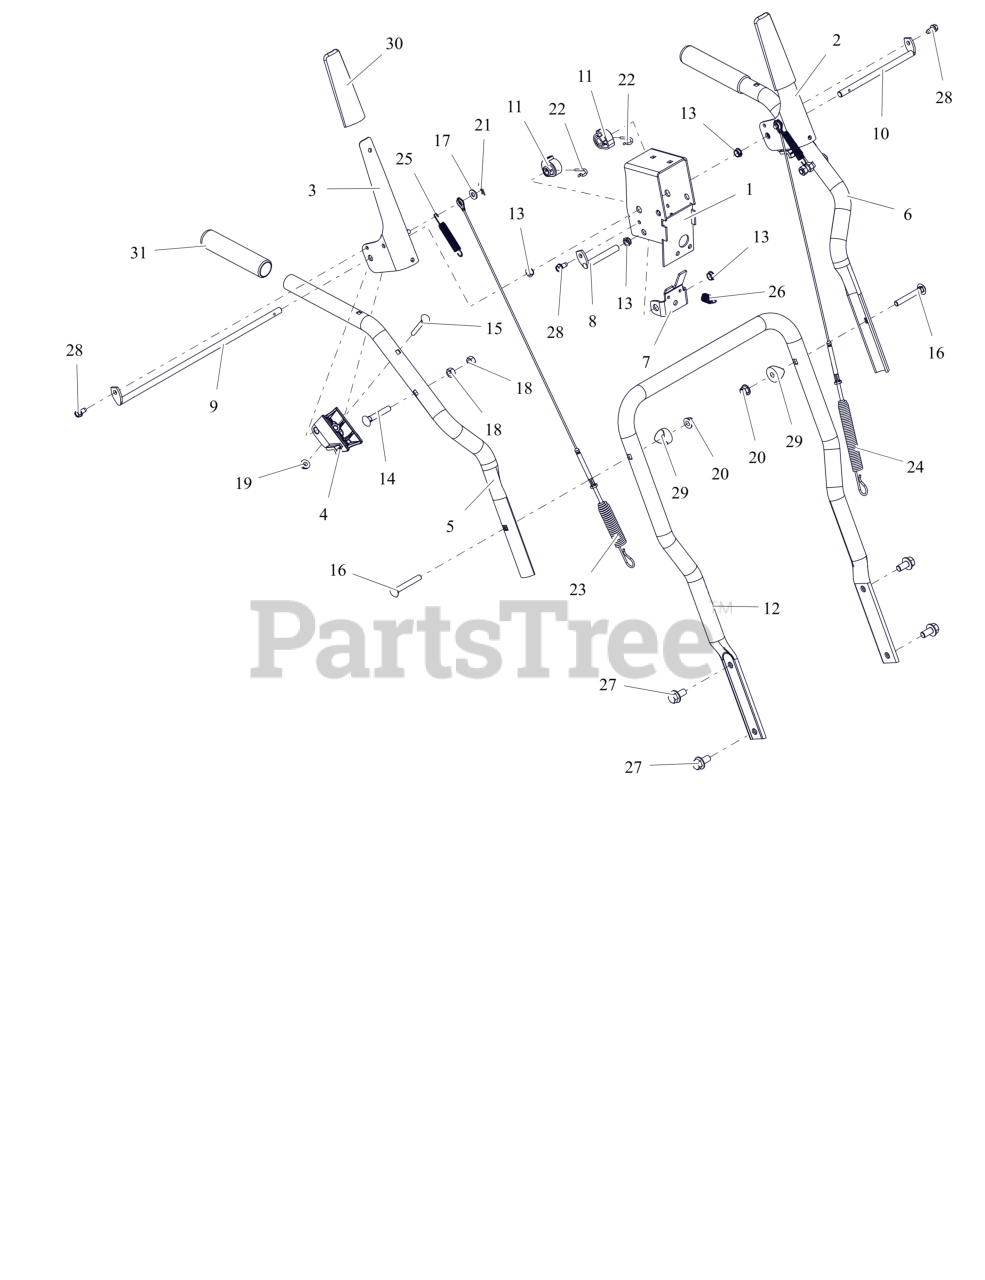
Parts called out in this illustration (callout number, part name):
1	WELDMENT, BRACKET INTERLOCK
2	LEVER, CLUTCH-LH
3	LEVER, CLUTCH-RH
4	BLOCK, CLUTCH PADDLE
5	HANDLEBAR, UPPER - RH (BLACK)
6	HANDLEBAR, UPPER - LH (BLACK)
7	BRACKET, INTERLOCK ARM
8	ROD, PIVOT - INTERLOCK
9	ROD, PADDLE MOUNT - LONG
10	ROD, PADDLE MOUNT - SHORT
11	CAM, INTERLOCK
12	HANDLEBAR, LOWER SMALL DASH (BLACK)
13	BUSHING, POLYLINER-.38 SNAPIN
14	BLT-RDHDXLSQNK .31-18X2.0 G5YZ
15	BLT-RDHDXLSQNK .25-20X2.0 G5YZ
16	BLT-RHSN.31-18X2.25 G5 TBZ 120
17	WSHR,FLT .281X.625X.065 ZCC
18	NUT,LK-CTR .31-18 GA ZCC
19	NUT-LK-CTR-FLG .25-20 ZC120
20	NUT-NYL-FLG.31-18 GF TBZ 120WR
21	PIN, HAIR #178 .06X.77 ZCC
22	PIN, SPRING CLIP
23	CABLE, AUGER (DELUXE & PRO)
24	CABLE, UPPER TRACTION
25	SPRING, EXTENSION
26	SPRING-EXT .047X.438X1.45
28	SCR-TAP .25-20X.50 HWH ZCC
29	SPACER, HANDLEBAR
30	COVER, PADDLE
31	GRIP, HANDLEBAR
